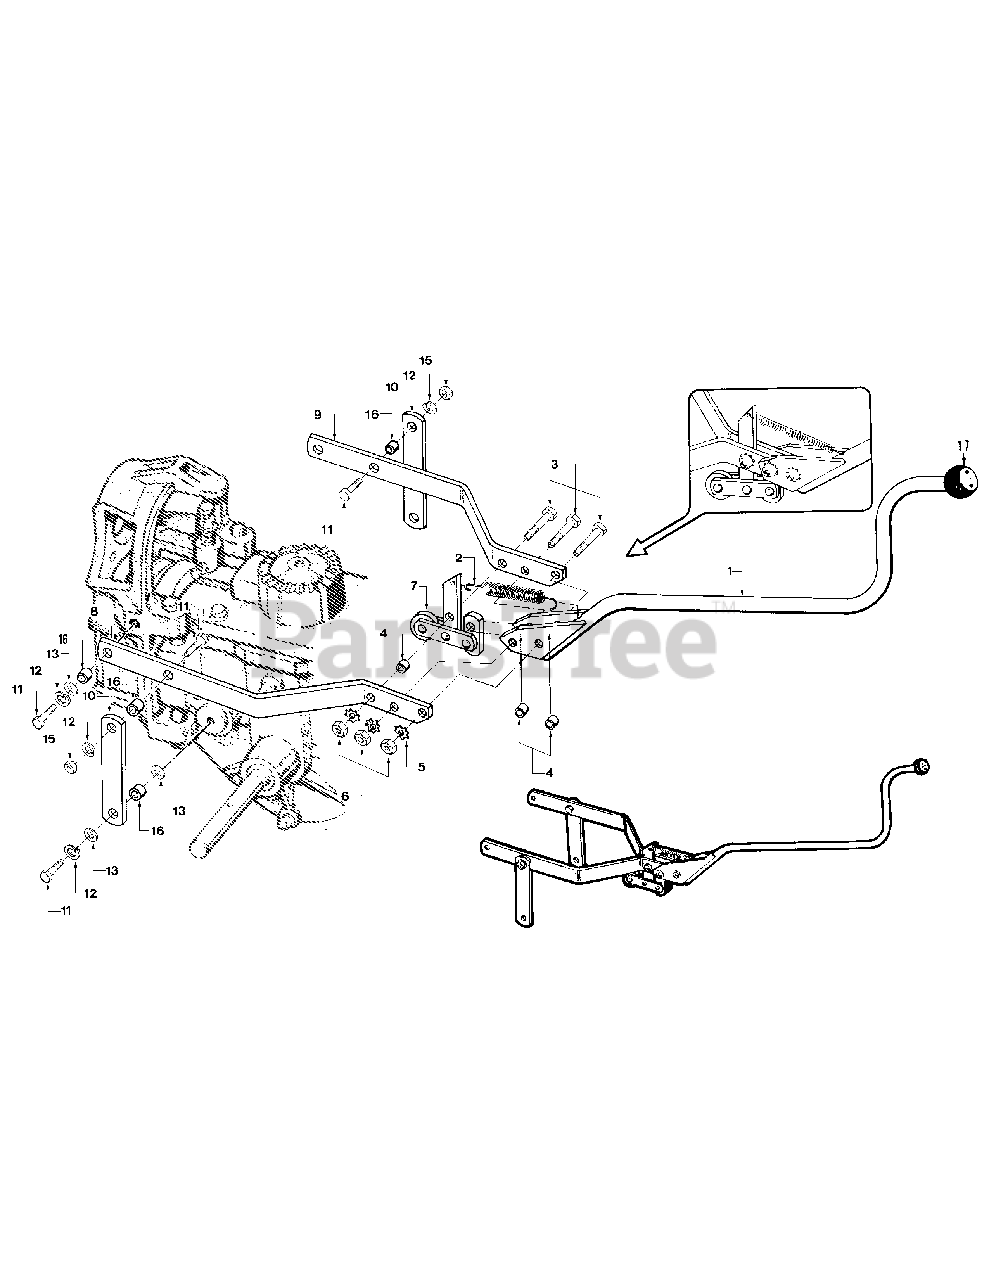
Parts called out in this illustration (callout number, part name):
1	Lever Assembly-Wheels/Tines/ PTO Drive (incl. Ref 17)
2	Spring-clutch pawl
3	Bolt-hex hd., 5/16-18 x 1-1/2"
4	Bushing-3/8"
5	Lockwasher-external tooth, 5/16"
6	Nut-hex, 5/16"-18
8	Yoke-left side
9	Yoke-right side
10	Link-yoke pivot, left & right 6-7/8" long
11	Bolt-hex hd., 3/8-16 x 1
12	Lockwasher-spring lock 3/8"
13	Washer-flat, 3/8", SAE
15	Nut-hex, 3/8"-16
16	Bushing-spacer, 19/64" (.300")
17	Knob
